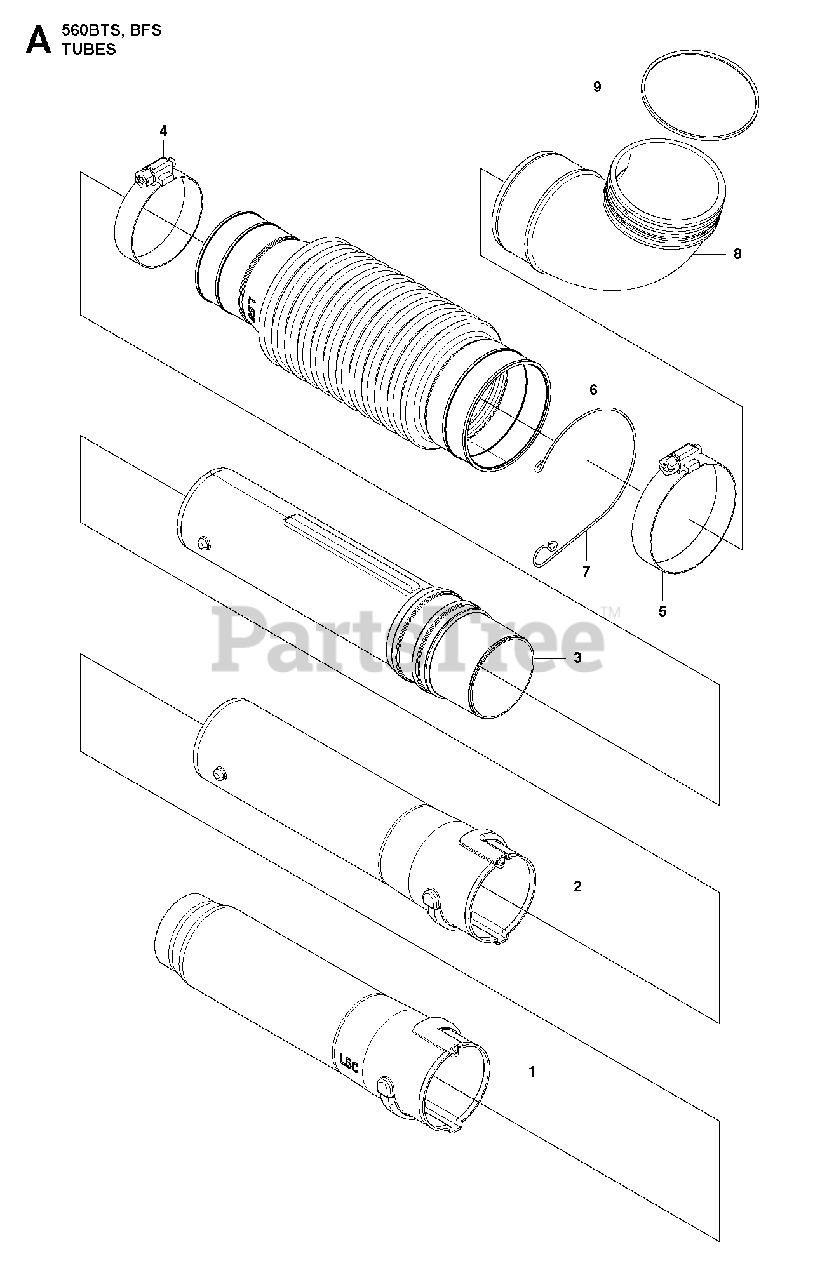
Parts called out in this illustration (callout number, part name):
3	SWIVEL JOINT
4	CLAMP(F96)
5	CLAMP(F115)
8	PIPE ELBOW
